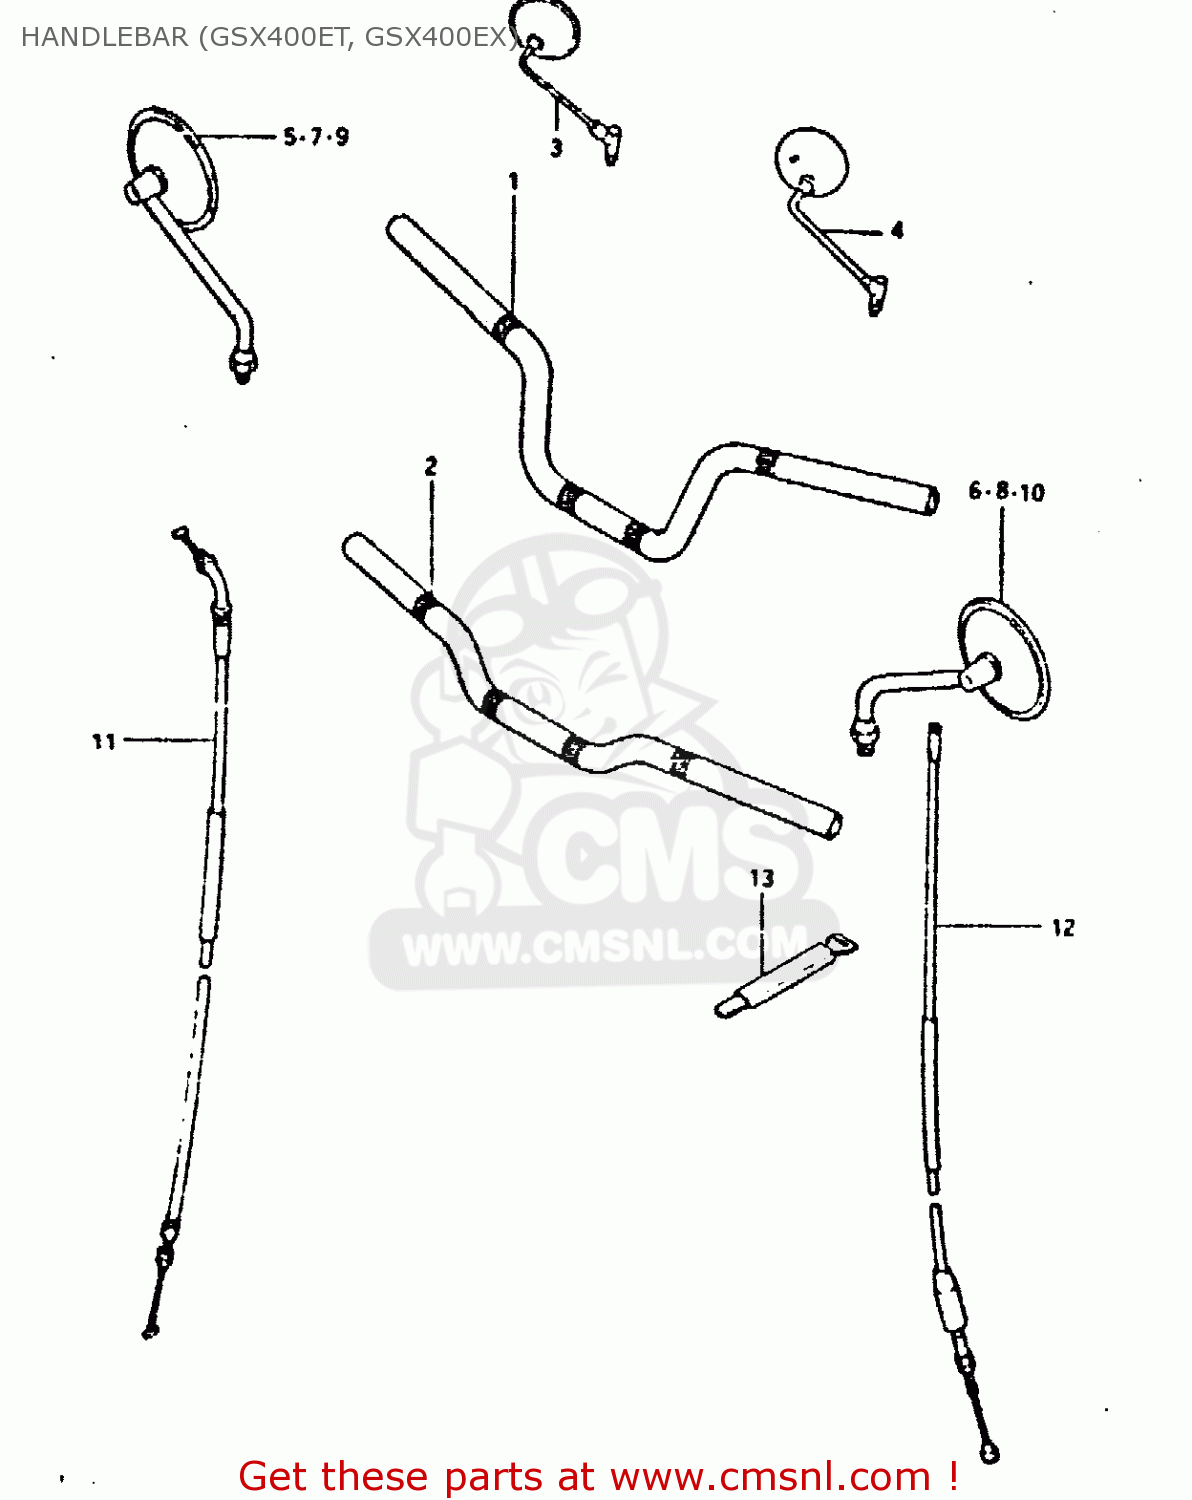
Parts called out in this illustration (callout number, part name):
1	HANDLEBAR
2	HANDLEBAR
3	MIRROR ASSY,RR VIEW
11	CABLE ASSY,CLUTCH
12	CABLE ASSEMBLY,THROTTLE
13	CLAMP
